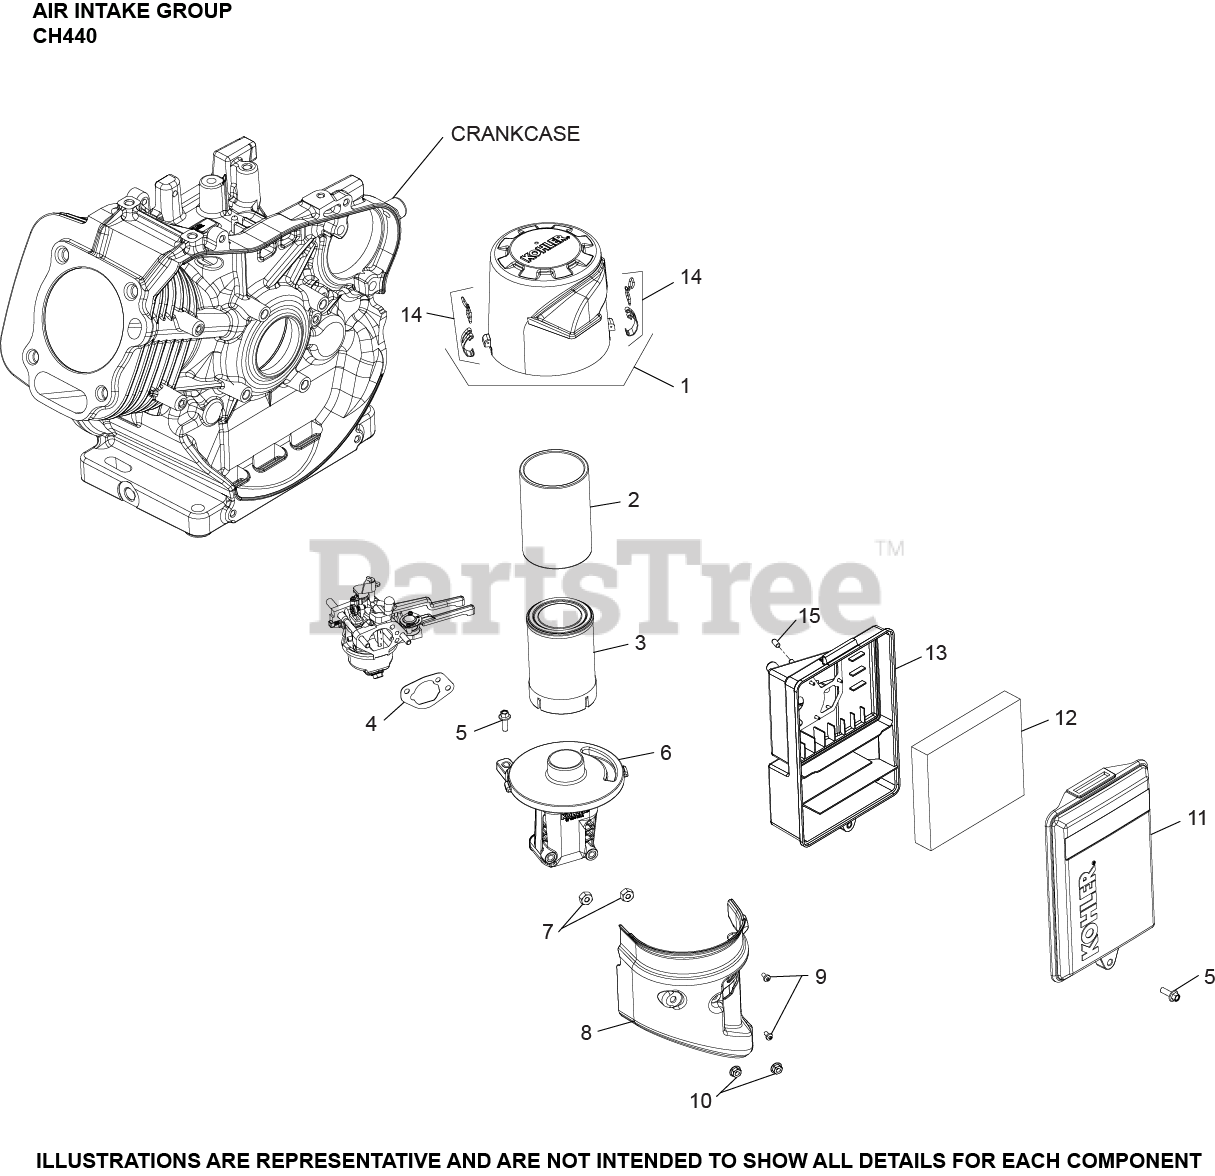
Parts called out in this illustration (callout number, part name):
4	GASKET, AIR CLEANER
5	SCREW, HEX FLANGE SLOTTED (M6) (CKY)
10	NUT, HEX FLANGE LOCK (M6)
11	COVER, AIR CLEANER
12	ELEMENT, AIR FILTER
13	BASE ASSEMBLY, AIR CLEANER
15	CAP, MASKING (CKY)
